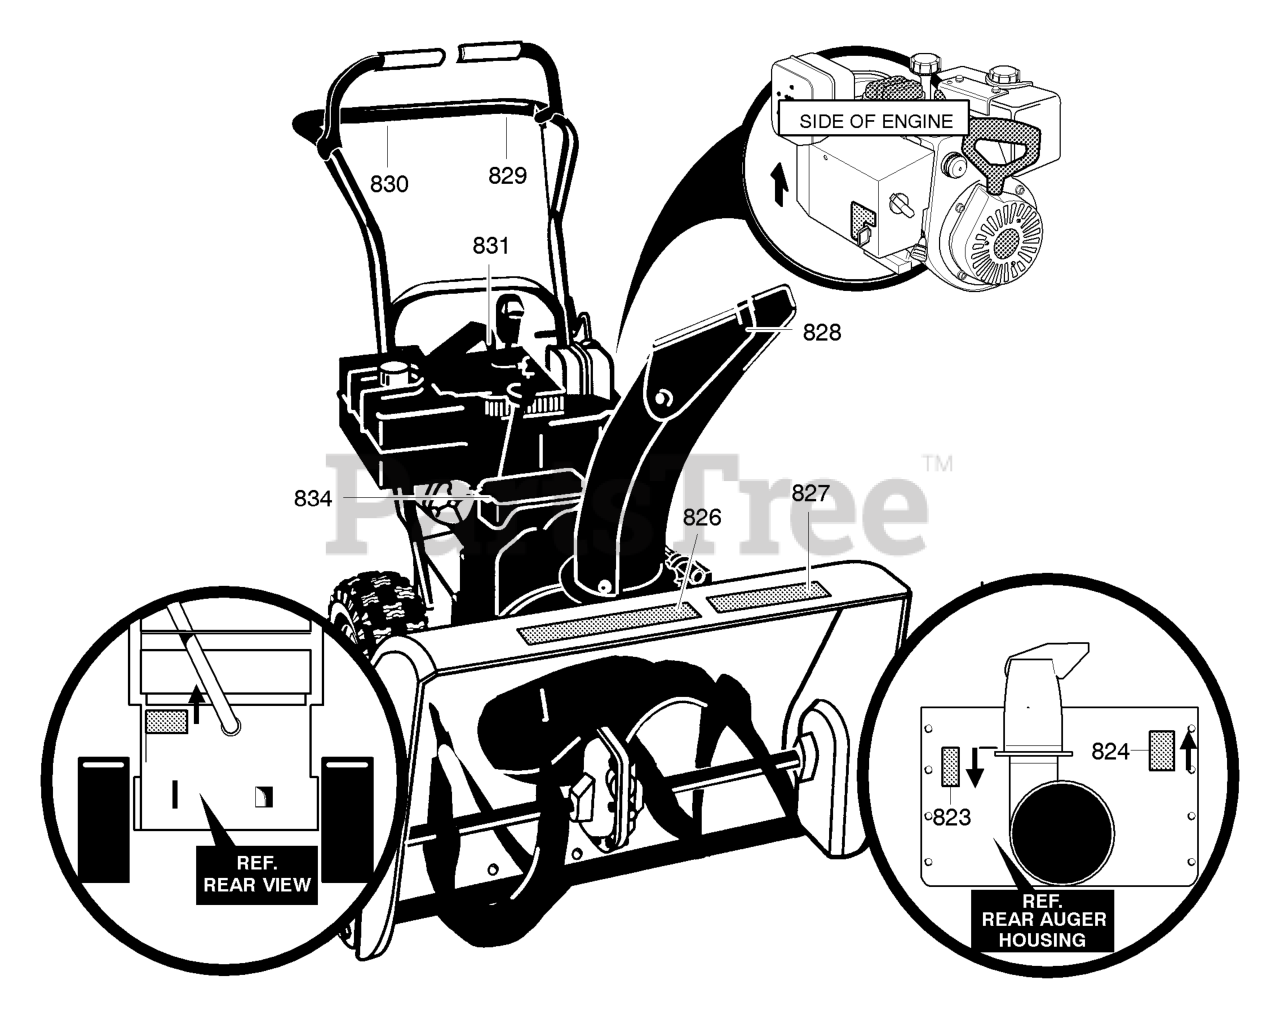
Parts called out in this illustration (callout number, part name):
823	DECAL, DANGER CHUTE HAND
824	DECAL, DANGER FOOT
826	DECAL, CRAFTSMAN GOLD
827	DECAL, 5.5/22
828	DECAL, STRIPE
829	DECAL, DRIVE CLUTCH
830	DECAL, AUGER CLUTCH
831	DECAL, GEAR SELECTOR
834	DECAL, TOOLBOX INFORMATION
